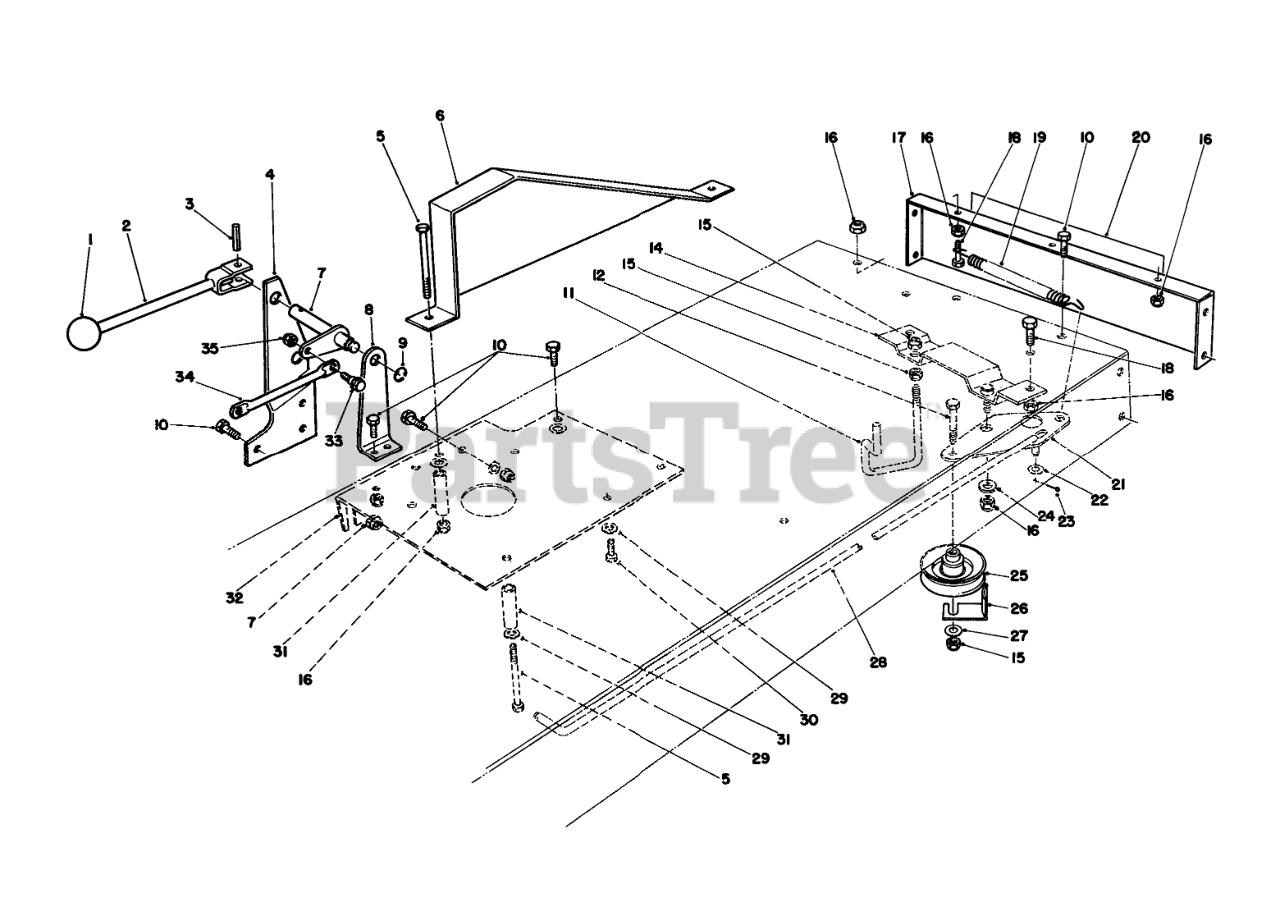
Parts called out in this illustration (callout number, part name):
2	Lever W.A.-Engage
3	PIN-ROLL
4	Pivot-Outer
5	SCREW-HH
6	CHAIN GUARD R
7	PIVOT SHAFT WA
8	Bracket-Pivot, Inner
9	RING-RETAINING, EXTERNAL
10	SCREW-HH
11	BELT GUIDE
12	SCREW-HH
14	TRACT SUPT BRKT WA B
15	NUT-LOCK, NI
16	NUT-LOCK, NI
17	REAR FRAME R
18	SCREW-HH
19	TRACTION SPRING
20	DECAL - REAR FRAME
21	TRACT PIVOT BRKT B
22	WASHER-FLAT
23	PIN-COTTER
24	WASHER-FLAT
25	PULLEY-IDLER
26	RETAINER-BELT
27	WASHER-FLAT
28	TRACTION ROD
29	WASHER-PLAIN
30	Screw-Mach. Hex. Hd.
31	OUTER TUBE SPACER
32	REINF PLATE R
33	SCREW-SHOULDER
34	LINK-BELLCRANK
35	NUT-HEX
